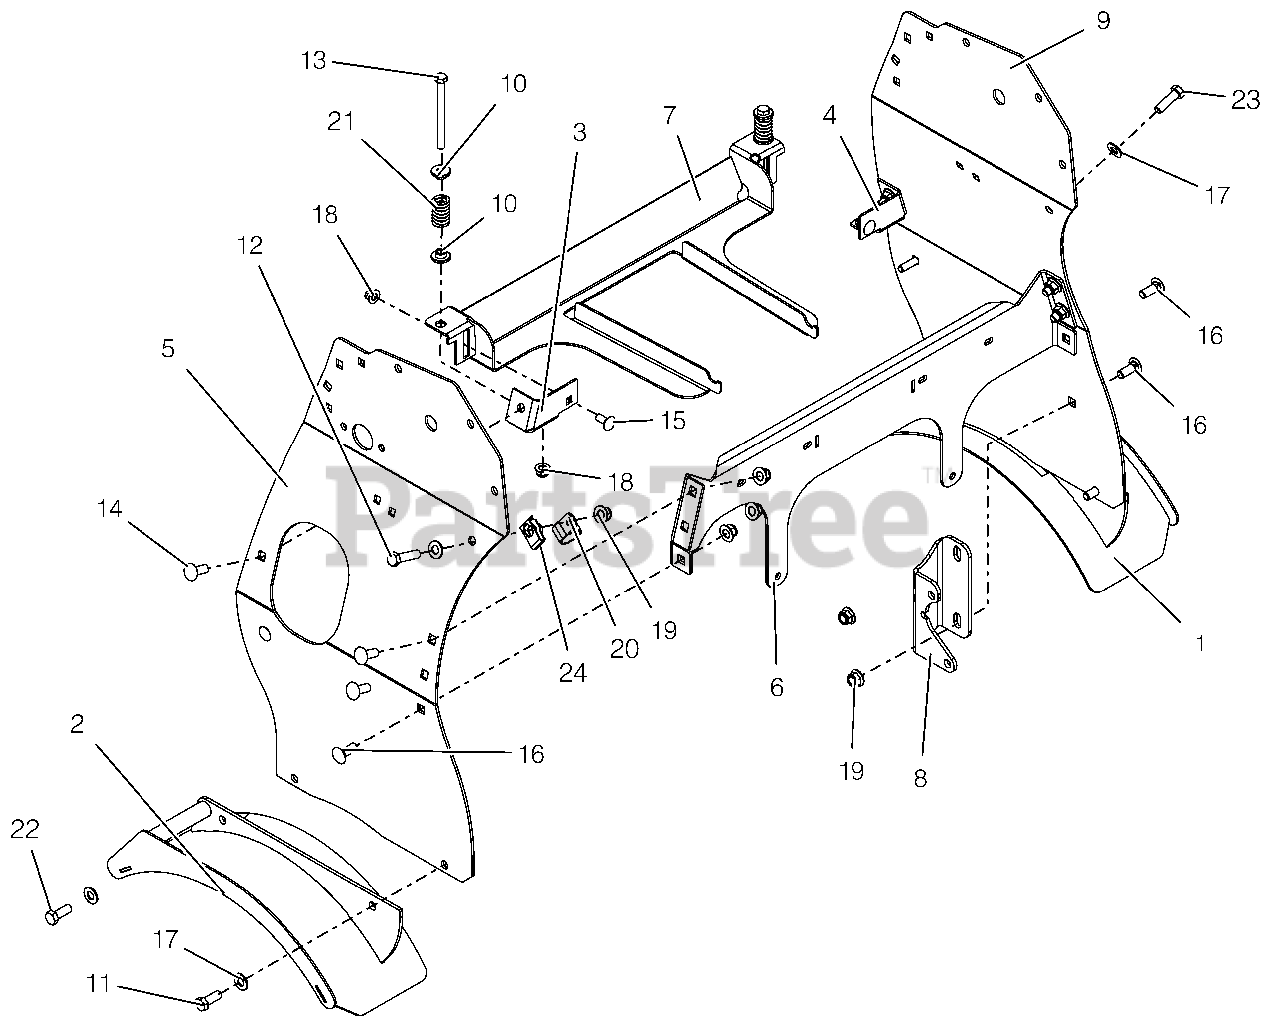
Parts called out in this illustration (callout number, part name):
1	BRKT, LH FENDER
2	BRKT, RH FENDER
3	MOUNT, FUEL TANK HOLD DOWN-RH
4	MOUNT, FUEL TANK HOLD DOWN-LH
5	KIT, SERVICE RH TOWER & DECAL
6	BRKT, CONTROL TOWER STIFFENER
7	HOLDDOWN, FUEL TANK
8	BRKT, TOWER SUPPORT
9	SIDE, LH PROSTANCE TOWER
10	BSHG-FLG .32X.500X.344X.880
11	@BLT-HEX .38-16X1.00 GR5 YWZC
12	@BLT-HEX .38-16X1.50 GR5 YWZC
13	BLT-HEX .312-18X3.75 YWZC
14	@BLT-RDHDSHSQNK.38-16X1.0 G5YZ
15	@BLT-RDHDSQNK .31-18X.75 G5YZ
16	@BLT-RDHDSQNK .38-16X1.00 G5YZ
17	@WSHR-FL-STL.406X.812X.065 YWZ
18	@NUT-LK-NYL-FLG .31-18 YWZC
19	@NUT-LK-NYL-FLG .38-16 YWZC
20	CLAMP, COUSHIONED STEEL REV
21	SG-COMP .125X.781X1.250
22	@BLT-HEX .38-16X1.00 GR5 YWZC
23	@BLT-HEX .38-16X1.25 GR5 YWZC
24	NUT-RTNR .375-16X.37
